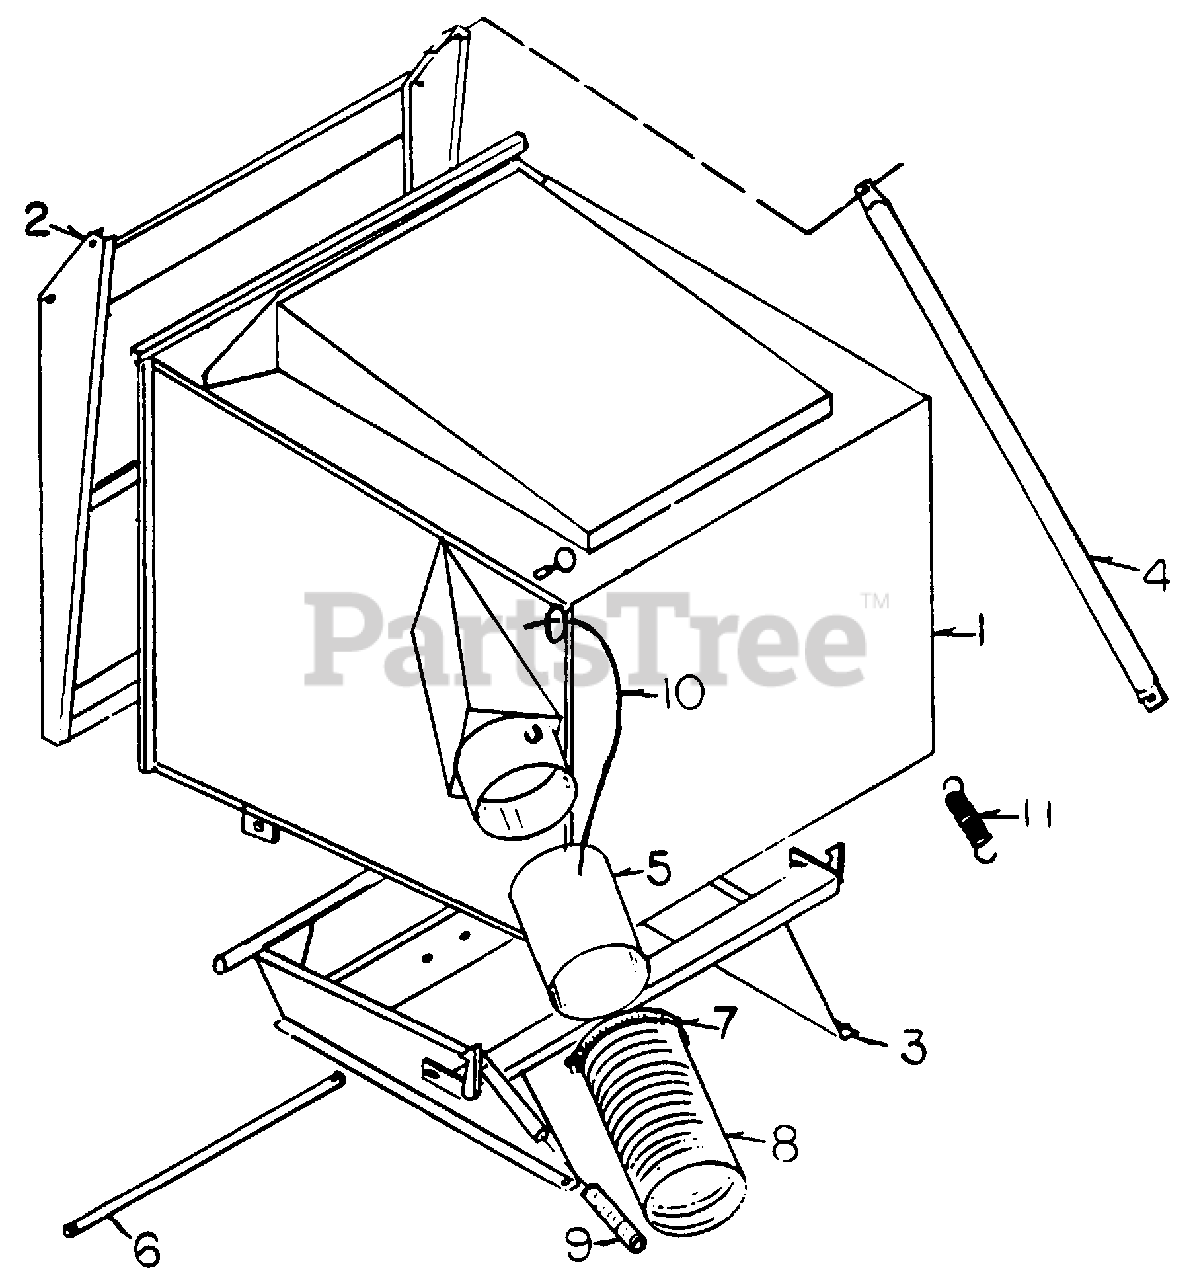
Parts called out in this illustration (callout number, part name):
1	Grass Box
3	Box Mount
4	Door Linkage, LH
5	Male Tube
8	Hose
9	Handle Grip
10	Male Tube Rope
